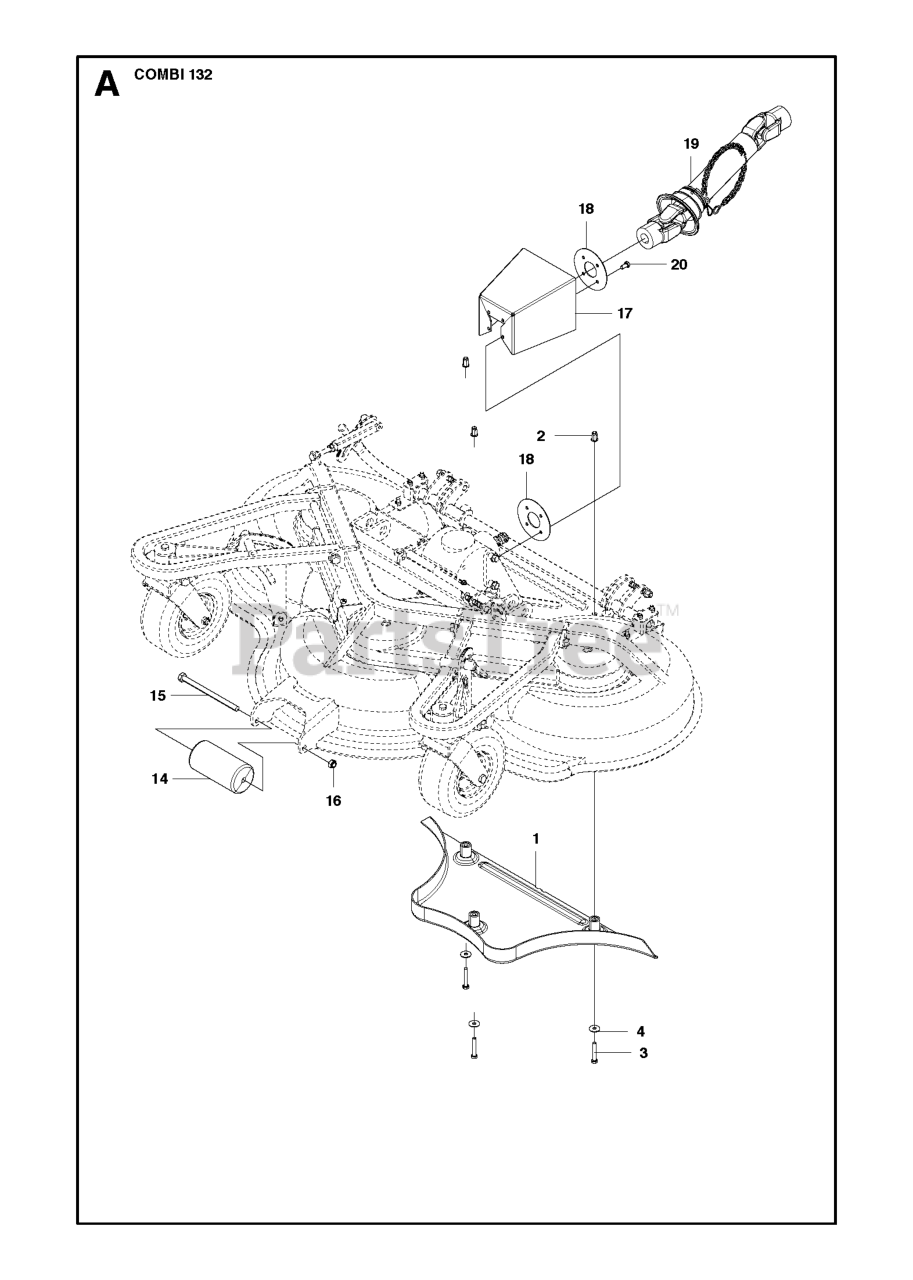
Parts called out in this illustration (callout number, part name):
2	BLIND RIVET NUT
14	ROLLER
20	BOLT - M8X16
